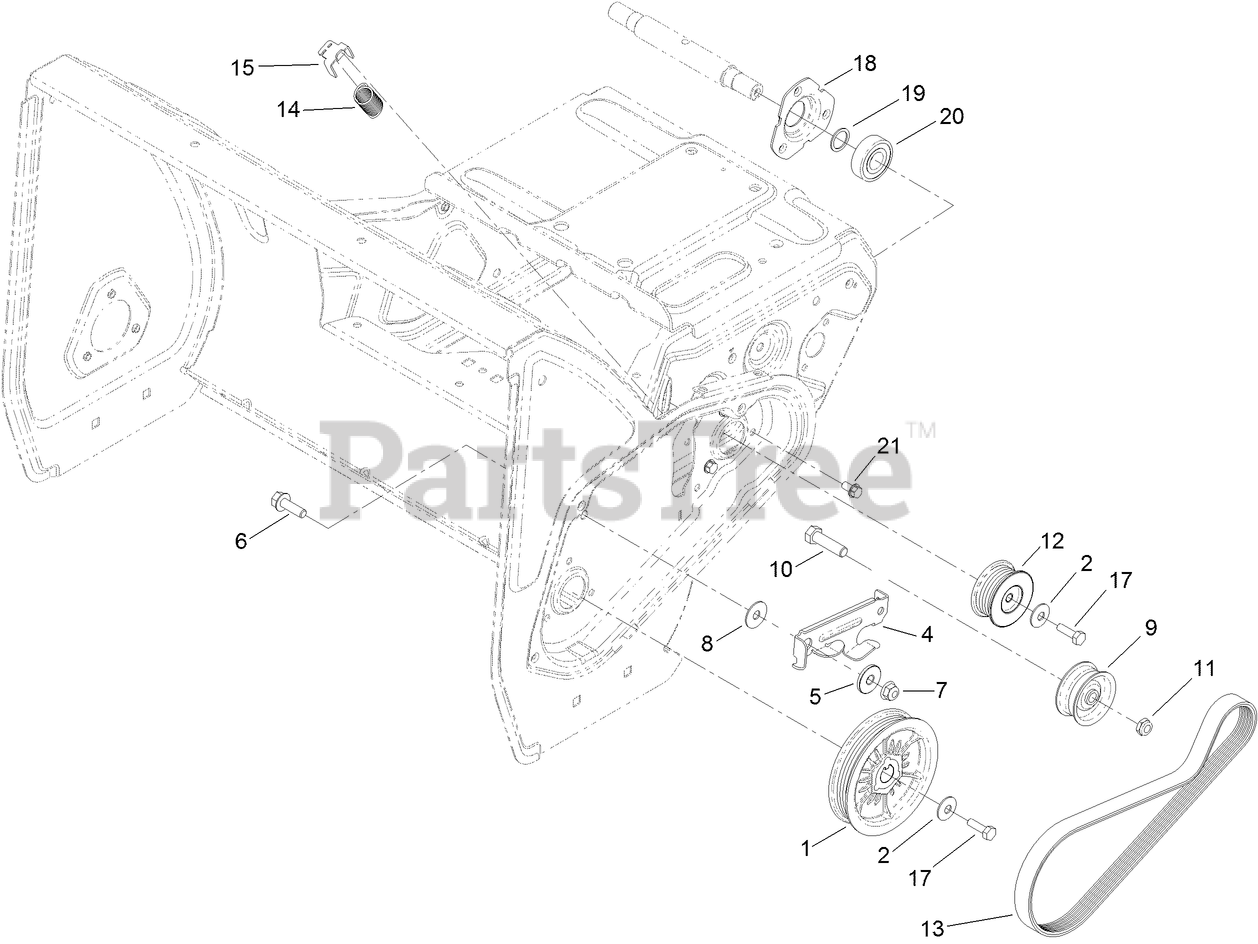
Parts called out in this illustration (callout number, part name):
1	PULLEY-ROTOR
2	WASHER-BELLEVILLE
4	ARM-ENGAGEMENT, ROTOR
5	BUSHING-IDLER
6	SCREW-HHF
7	NUT-HF, NI
8	WASHER
9	PULLEY-IDLER, FLAT
10	SCREW-HH
12	PULLEY-JACKSHAFT, ROTOR
13	BELT-POLY V
14	SPRING-EXTENSION
17	SCREW-HH
19	WASHER-THRUST
20	BEARING-BALL
21	SCREW-HWH
